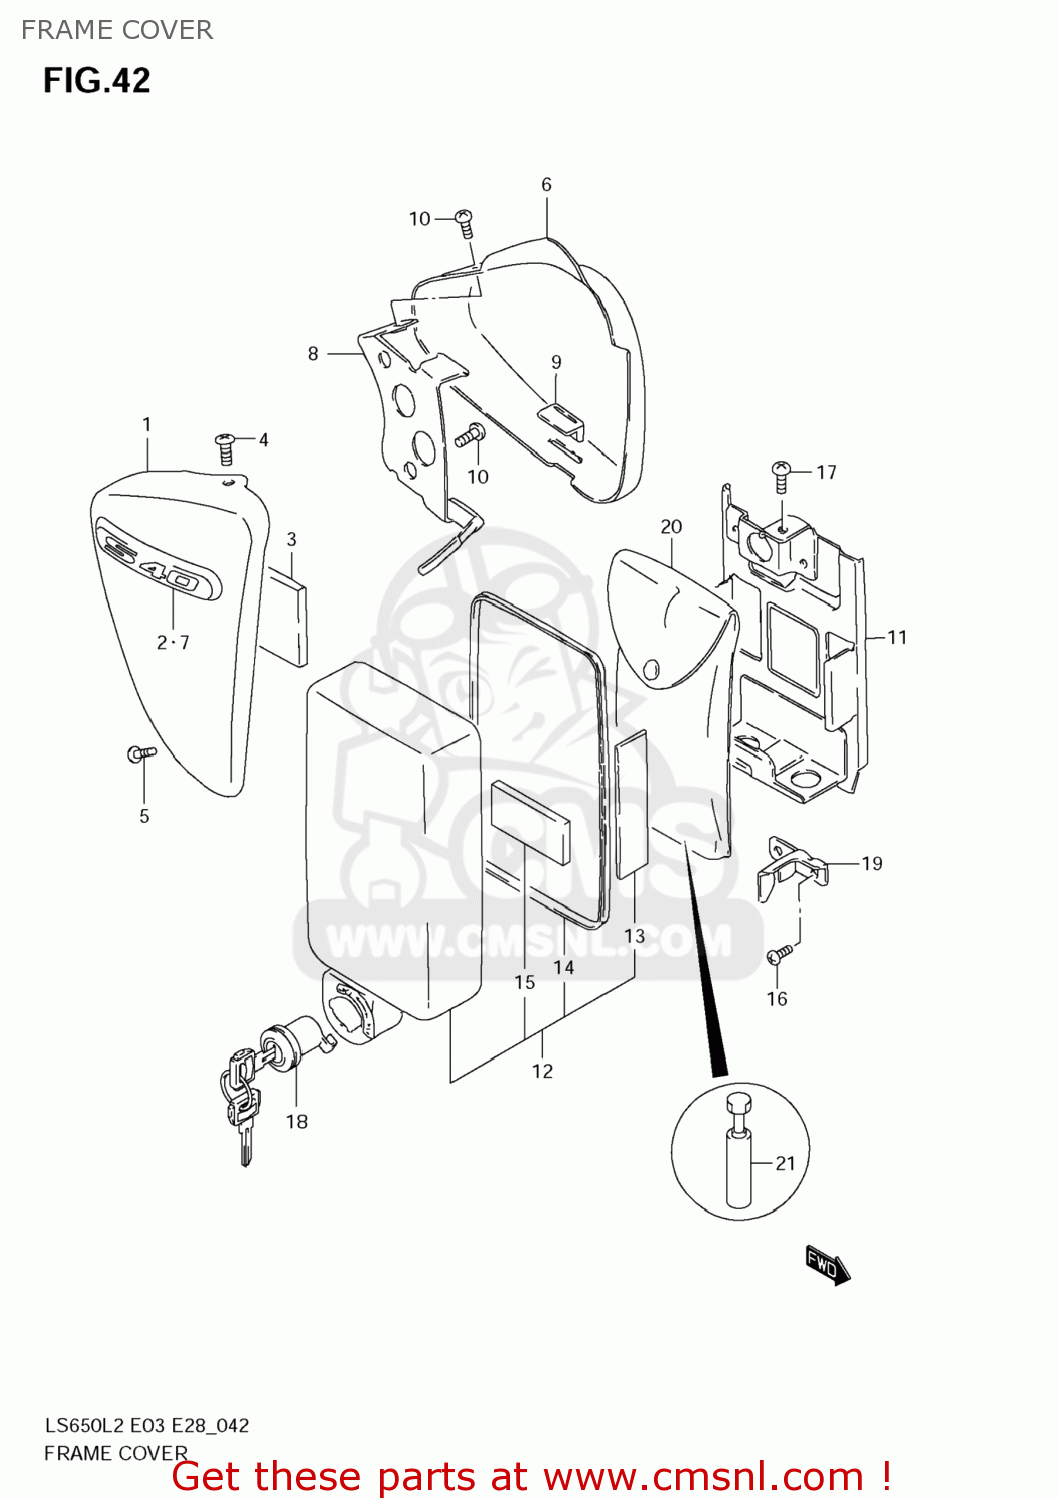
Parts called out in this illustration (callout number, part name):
1	COVER ASSY,FRAME,R(SILVER)
2	EMBLEM,FRAME COVER
3	PAD
4	SCREW
5	SCREW
6	COVER ASSY,FRAM
7	EMBLEM,FRAME COVER
8	BRACKET,FRAME COVER,L
9	CUSHION,FRAME COVER
10	SCREW
11	HOLDER,TOOL
12	COVER,TOOL HOLDER
13	PROTECTOR(20X90)X2
14	MOLDING
15	PROTECTOR(20X50X11)
16	SCREW
17	SCREW, CENTER SHAFT
18	LOCK SET,TOOL HOLDER
19	PLATE,TOOL HOLDER LOCK
20	TOOL ASSY
21	GAUGE ASSY,TENSION
